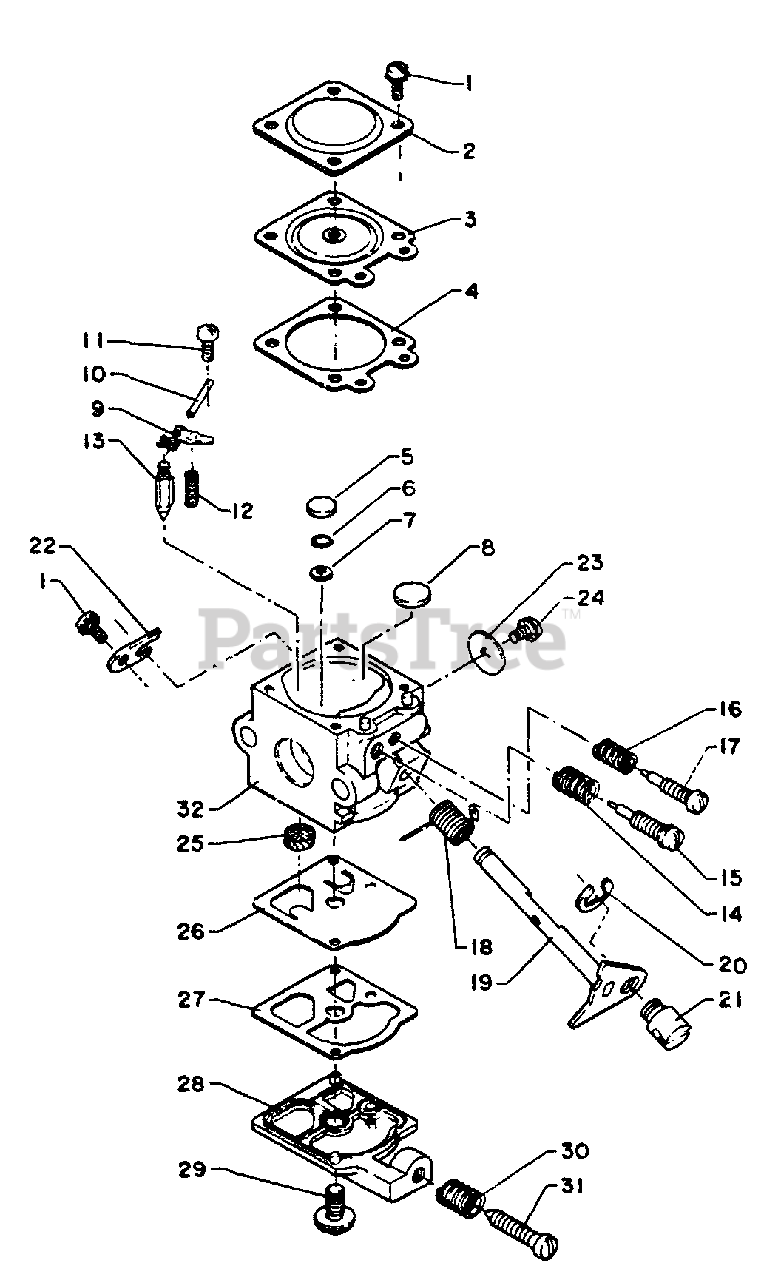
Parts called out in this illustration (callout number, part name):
1	REPAIR KIT, CARBURETOR
2	COVER, METERING DIAPHRAGM
3	DIAPHRAGM, METERING
4	GASKET, METERING
5	PLUG, WELCH
6	RING, RETAINING
7	STRAINER
8	PLUG, WELCH
9	LEVER, METERING
10	PIN, METERING LEVER
11	SCREW
12	SPRING, METERING LEVER
13	VALVE, INLET NEEDLE
15	NEEDLE, HIGH SPEED
17	NEEDLE, LOW SPEED
18	SPRING, THROTTLE RETURN
19	SHAFT, THROTTLE
20	RING, RETAINING
22	CLIP, THROTTLE SHAFT
23	VALVE, THROTTLE
25	STRAINER
28	COVER, FUEL PUMP
31	SCREW, IDLE ADJUST
32	BODY, CARBURETOR
